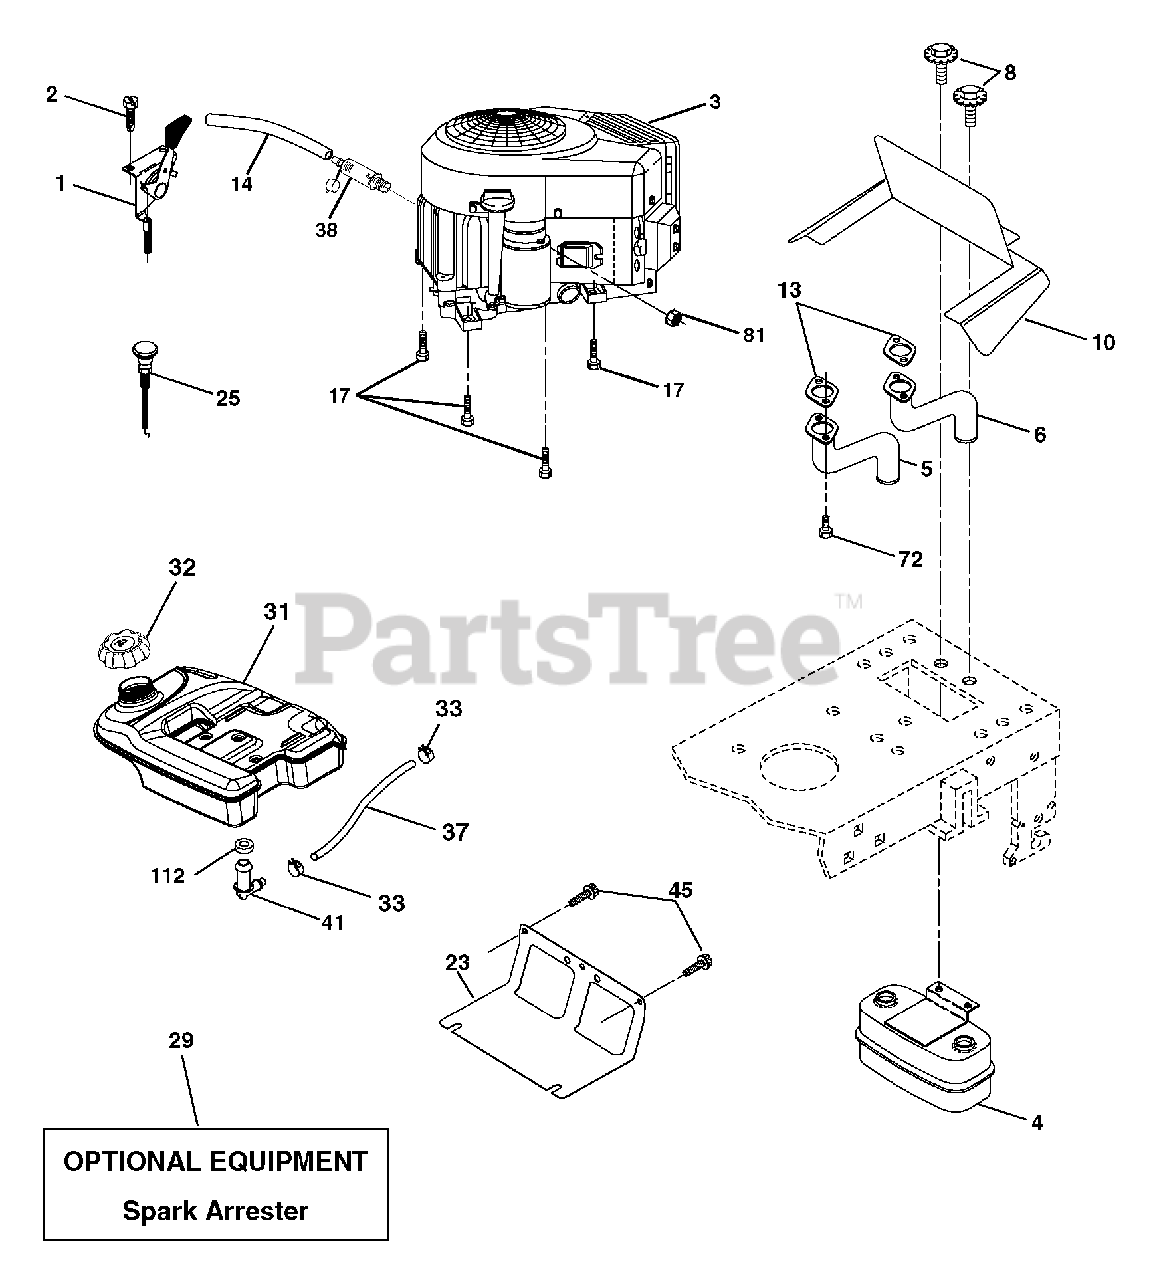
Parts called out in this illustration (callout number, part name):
1	Control Throttle
2	Screw 1/4-20 x 1/2
4	Muffler Asm Twin Lo-Tone
5	Pipe Exhaust LH
6	Pipe Exhaust RH
8	Bolt 5/16-18 unc x 3/4 w/Sems
10	Shield
13	Muffler Gasket
14	Tube Drain Oil Easy
17	Screw Thdrol 3/8-16 x 1-1/2
23	Shield Heat
25	Choke Control
29	Kit Spark Arrestor (Flat Scrn)
31	Tank Fuel 4.0 Rear
32	Cap Asm Fuel
33	Clamp Hose Black
37	Line Fuel
38	Plug Drain Oil
41	Stem Tank Fuel
45	Screw Hexwsh Thdr 3/8-16 x 3/4
72	Screw Socket Head 5/16-18 x 1
112	Bushing
116	Nut Hex Flange Toplock M8-1.25
